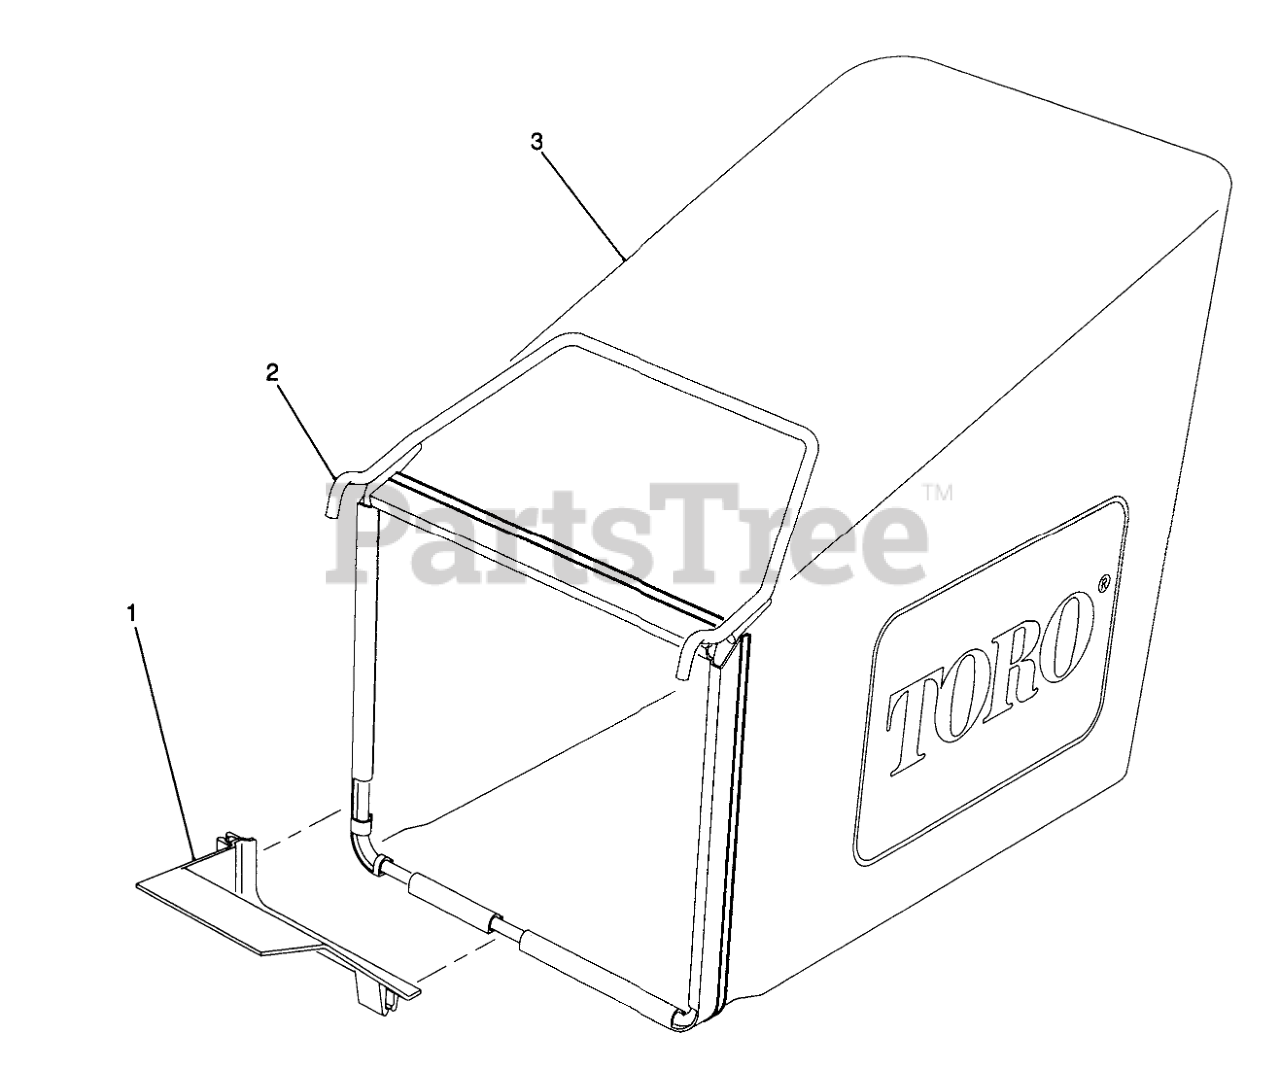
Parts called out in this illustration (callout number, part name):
1	BAG RAMP
2	Frame
3	GRASS BAG ASSEMBLY
